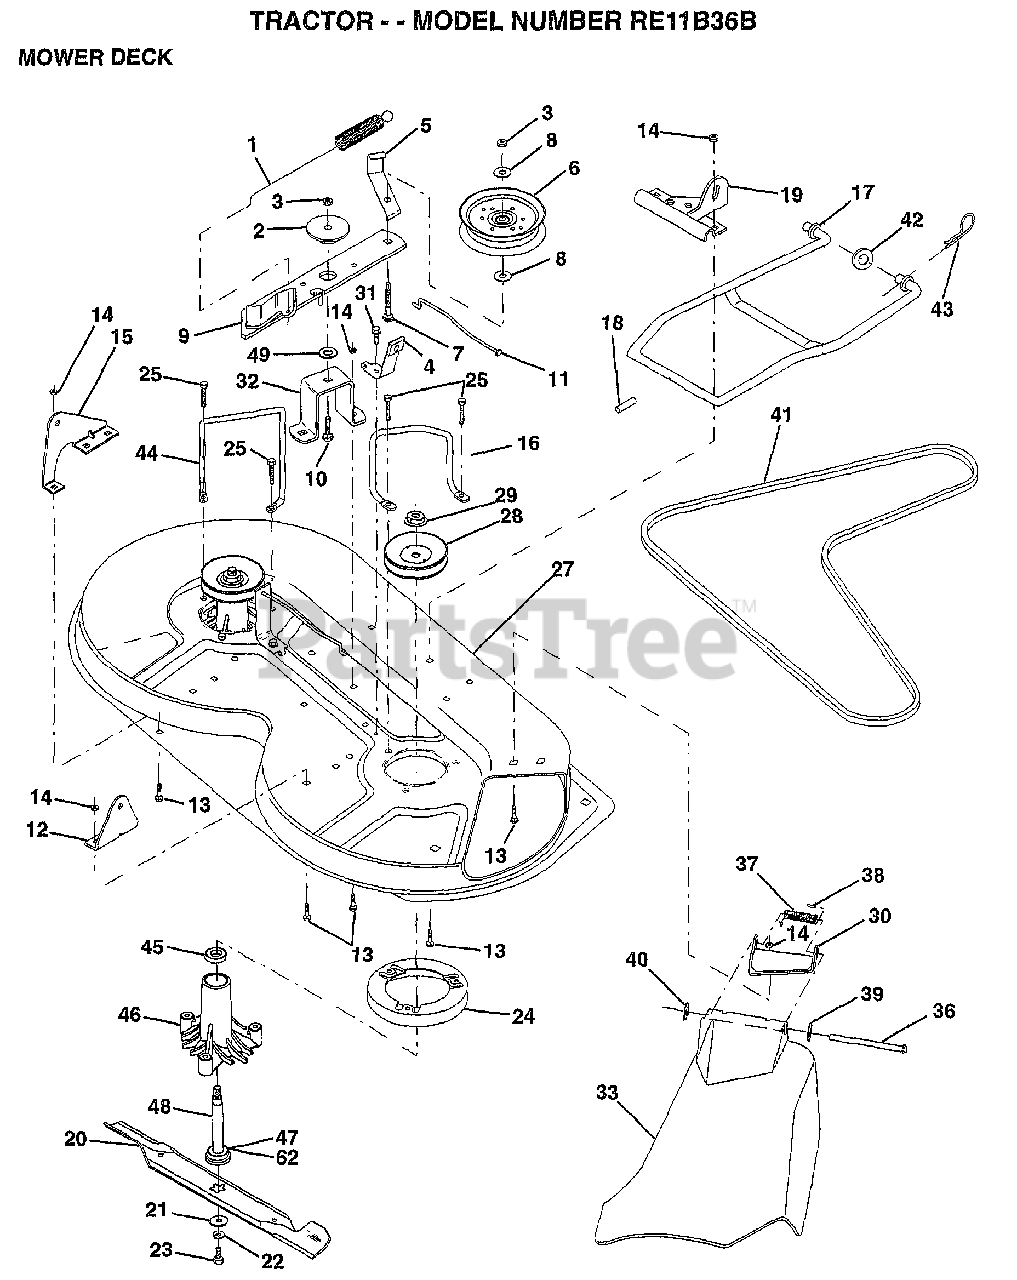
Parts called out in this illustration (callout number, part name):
1	SPRING CLUTCH MWR
2	SPACER RETAINER
4	BRAKE ASM
5	IDLER BELT GUIDE
6	PULLEY IDLER
7	BOLT
8	WASHER
10	BOLT.3/8-14X1.25
11	BRAKE ROD
12	"BRKT,LIFT REAR"
13	BOLT
15	"BRKT,LIFT REAR LH"
16	"KEEPER-BELT,RH"
17	MOWER LINK STAB
18	"PIN,GROOVE"
19	"BRKT,LINK STABILI"
20	"BLADE.36"" HIPERF"
21	WASHER.HARD.BLADE
23	BLADE BOLT
24	STRIPPER RND MWR
25	"SCREW-THD ROLL,WA"
27	"HOUSING-MOWER,36"""
28	PULLEY.MAND.36/46
31	SCREW LT
32	"SUPT,IDLER ARM"
36	HINGE ROD
37	SPRING TORSION
38	CAP-SLEEVE LT
39	WASHER
40	NUT PUSH M
41	V-BELT.PRIM.78.5.
43	RETAINER.SPRING
44	KEEPER BELT LH
45	BEARING
46	HSG ASM MANDREL
47	BEARING.BALL
49	HARDENED WASHER
62	WASHER.FELT.
